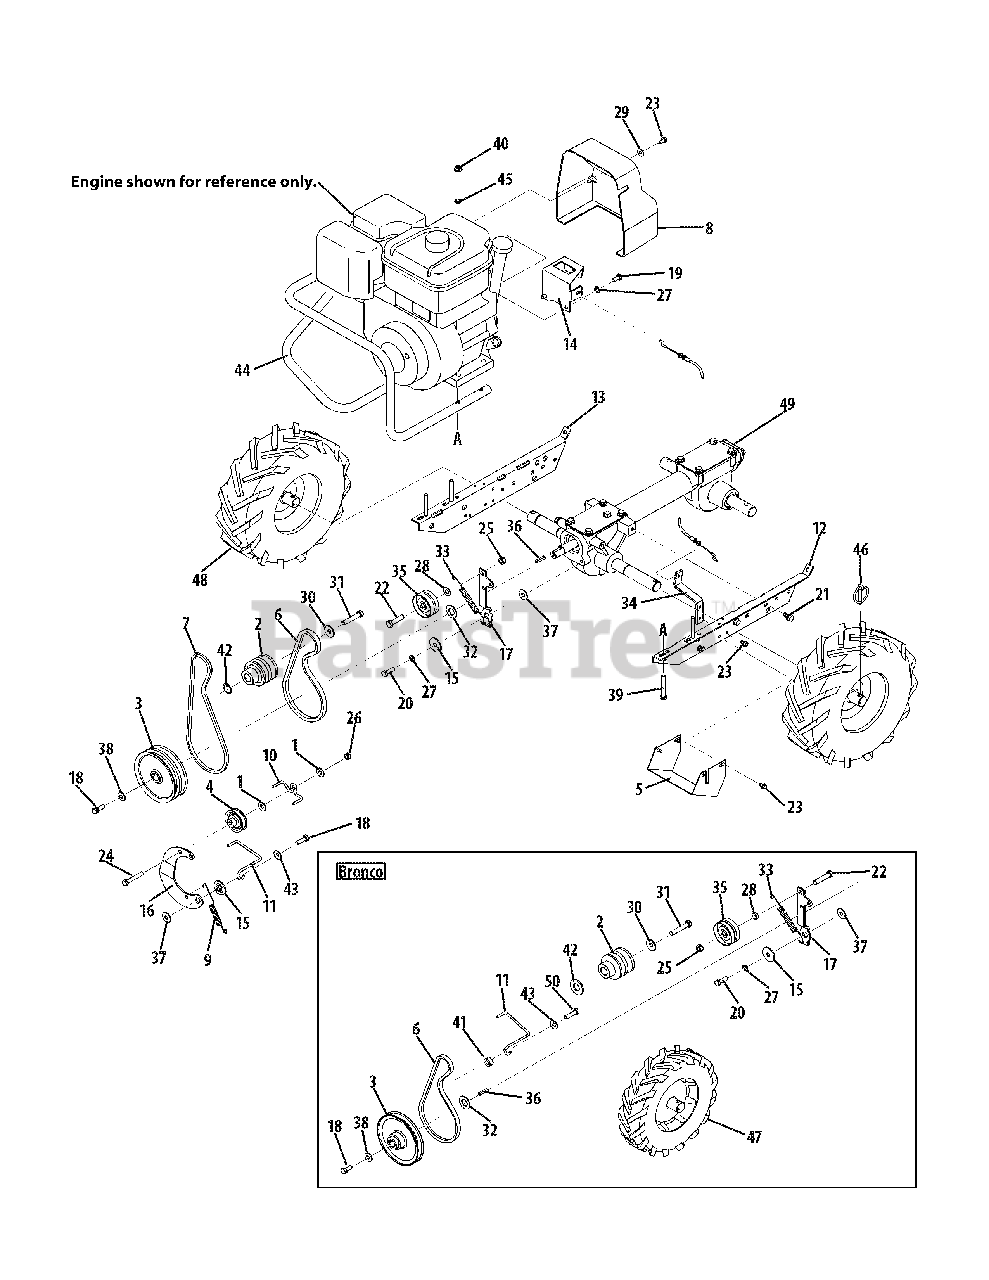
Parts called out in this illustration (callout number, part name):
1	Flat Washer, 5/16
2	Engine Drive Pulley
3	Transmission Pulley
4	Reverse Idler Pulley
6	Forward Drive Belt
7	Reverse Drive Belt
8	Belt Cover
9	Reverse Return Spring
10	Belt Guide
11	Belt Guide
12	Engine Bracket Left
13	Engine Bracket Right
16	Reverse Idler Arm
18	Hex Head Screw, 5/16-24 x 1
19	Hex Head Screw, 5/16-24 x 5/8
20	Hex Head Screw, 5/16-18 x 1
21	Hex Head Screw, 5/16-18 x /
22	Hex Head Screw, 3/8-16 x 1-3/4
22	Hex Head Screw, 3/8 -16 x 1.50
23	Self-Tapping Screw, 1/4-20 x 1/2
24	Hex Head Screw, 5/16-18 x 2
25	Lock Nut, 3/8 -16
26	Lock Nut, 5/16-18
27	Lock Washer, 5/16
28	Spacer, .380 ID x .625 OD x .21
28	Flat Washer, .406 x .812 x .051
29	Flat Washer, .260 x .720 x .060
30	Bell Washer, .396 x 1.140 x .095
31	Hex Head Screw, 3/8 -24 x 1.50
32	Support Washer, .690 x 1.250 x .075
33	Forward Return Spring
36	Key, 3/16" x 1"
37	Flat Washer, .344 x 1.00 x .063
38	Belleville Washer, .827 x .331 x .098
39	Hex Screw, 5/16-18 x 1.50
39	Hex Screw, 5/16-18 x 2-1/4
40	Hex Lock Nut, 5/16-18
41	Shlder Spacer, .315 x .750 x .375
42	Flat Washer, .75 x 1.5 x .125
42	Flat Washer, .786 x 1.000 x .031
43	Bell Washer, .340 x .872 x .060
45	Speed Nut, 5/16-18
46	Klik Pin
47	Complete Wheel Ass., 10 x 2.75
48	Complete Whl. Ass., 13 x 5 x 6
48	Rim Assembly
48	Valve
49	Transmission Assembly
50	Hex Head Screw, 5/16-24 x 1.25
